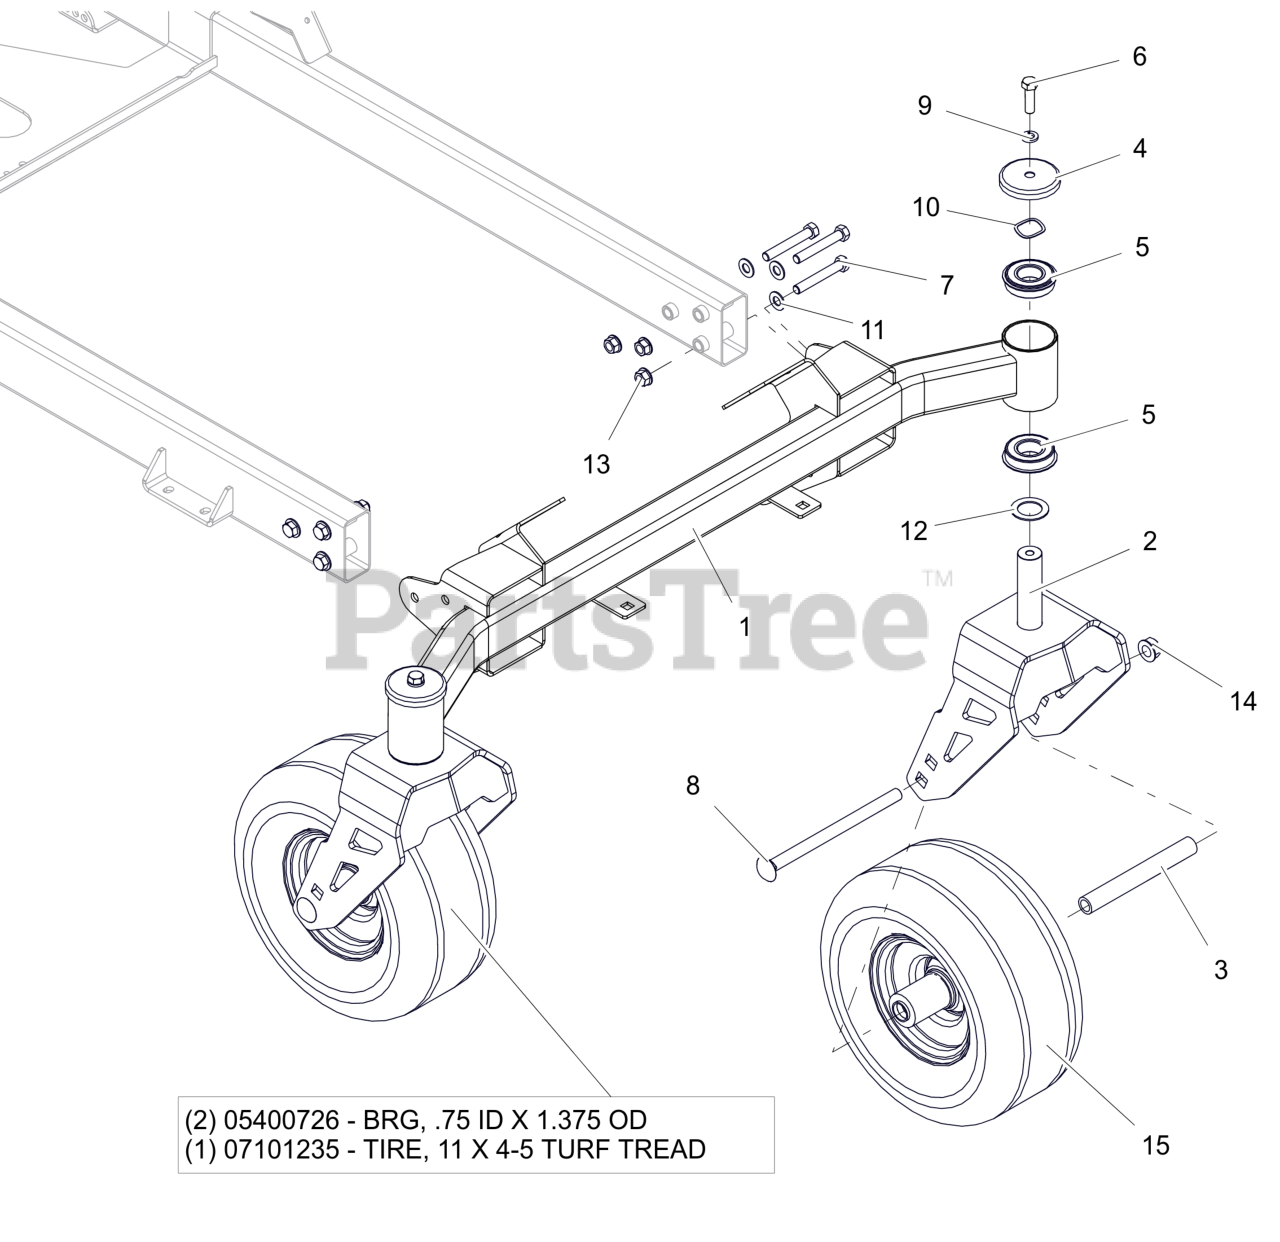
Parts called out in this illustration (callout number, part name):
1	WMT-FRONT AXLE-X/XL
2	WLDMT, CASTER FORK-XL (ORANGE)
3	SPACER, FRONT WHEEL (WIDE 6.0)
4	SHIELD, AXLE BEARING
5	BEARING, BALL -2.000 OD X 1.000 ID X .5625 W/RING
6	BLT, HEX .38-16X1.25 G5 ZCC
7	BLT, HEX .38-16X2.50 G8 ZCC
8	BLT, RHSN .50-13X7.50 G5 ZCC
9	WSHR,LK-REG .375X.094 ZCC
10	WSHR-WAVE 1.0X1.25X.028 .145FH
11	WSHR,FLT-HRD.406X.812X.055 MZC
12	WSHR-HRD-THRS 1.007X1.542X.062
13	NUT-LK-TOP-FLG .375-16 GG ZCC
14	NUT-LK-TOP-FLG .500-13 GF ZCC
15	TIRE/WHEEL ASSY 11X6-5
15	BRG, .75 ID X 1.375 OD
15	TIRE, 11X4-5 TURF TREAD
